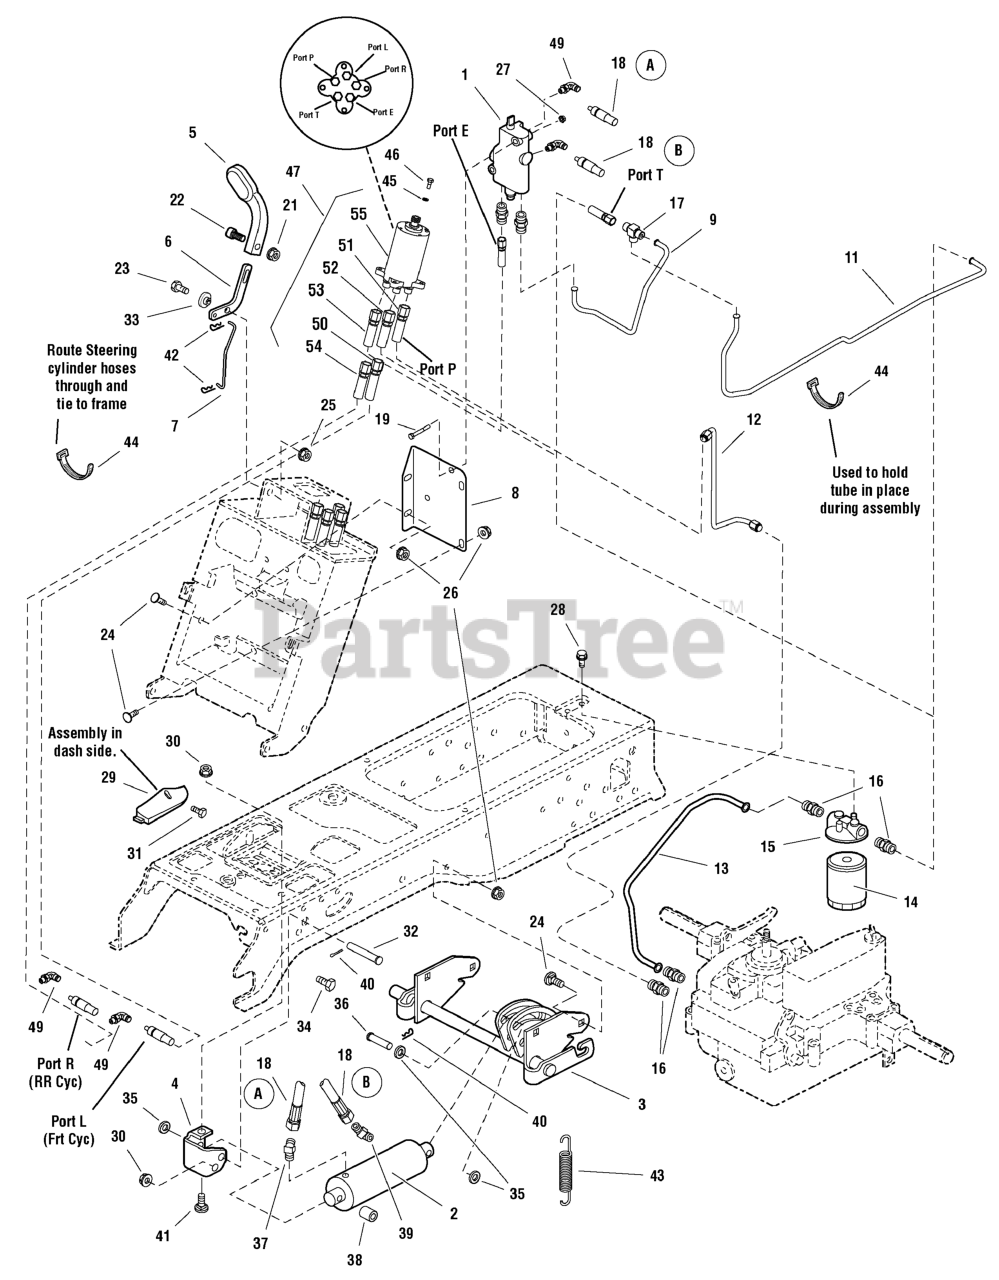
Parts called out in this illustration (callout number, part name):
1	CONTROL VALVE, Single Spool
2	CYLINDER, Hydraulic
3	SHAFT ASSEMBLY, Lift
4	SUPPORT, Cylinder
5	HANDLE, Lift
6	LEVER, Hydraulic
7	ROD, Curved Link
8	SUPPORT, Control
9	TUBE, Hydraulic, 5 Bends
11	TUBE, Hydraulic, 8 Bends
12	TUBE, Hydraulic 3 Bends
13	TUBE, Hydraulic
13	TUBE, Hydraulic, 5 Bends
14	FILTER, Oil
15	BASE, Oil Filter
16	FITTING, Straight
17	FITTING, Tee, 3 Ports / Hydraulic Hose
18	HOSE ASSEMBLY, Hydraulic
19	CAPSCREW, Hex Head, 1/4-20 x 2 G5
21	NUT, Hex Lock ESNA Light 1/4-20
22	SCREW, Torx Plus Socket Head 1/4-20 x 7/8
23	CAPSCREW, Hex Head, 5/16-18 x 1
24	BOLT, Carriage, 5/16-18 x 3/4, G5
25	NUT, Hex Lock ESNA Light 5/16-18
26	NUT, Hex KEPS 5/16-18
27	NUT, Hex KEPS 1/4-20
28	SCREW, Hex Whiz Lock Flange, 1/4-20 x 1/2
29	COVER, Dash ABS
30	NUT, Hex KEPS 3/8-16
31	SCREW, Pan Head Torque, #8-16 x 1/2, Plastite
32	PIN, Clevis
33	SPACER, Pivot
34	CAPSCREW, Hex Head 3/8-16 x 1 G5
35	WASHER, 1/2
36	PIN, Flat Head Drilled
37	FITTING, Elbow 1/2
39	FITTING, Elbow 1/2
40	CLIP, Hair Pin
41	BOLT, Carriage, 3/8-16 x 1, G5
42	PIN, Cotter 5/8 x 3/4
43	SPRING, Extension
44	TIE, Self Locking
45	LOCKWASHER, Spring 1/4
46	CAPSCREW, Hex Head
47	POWER STEERING ASSEMBLY, 32CC, 5 Ports
49	FITTING, Hose Elbow Perma Push 9/16-18
50	HOSE ASSEMBLY, 46"
51	HOSE ASSEMBLY, 26"
52	HOSE ASSEMBLY, 18"
53	HOSE ASSEMBLY, 20"
54	HOSE ASSEMBLY, 50"
55	POWER STEERING UNIT, 32CC, 5 Ports
